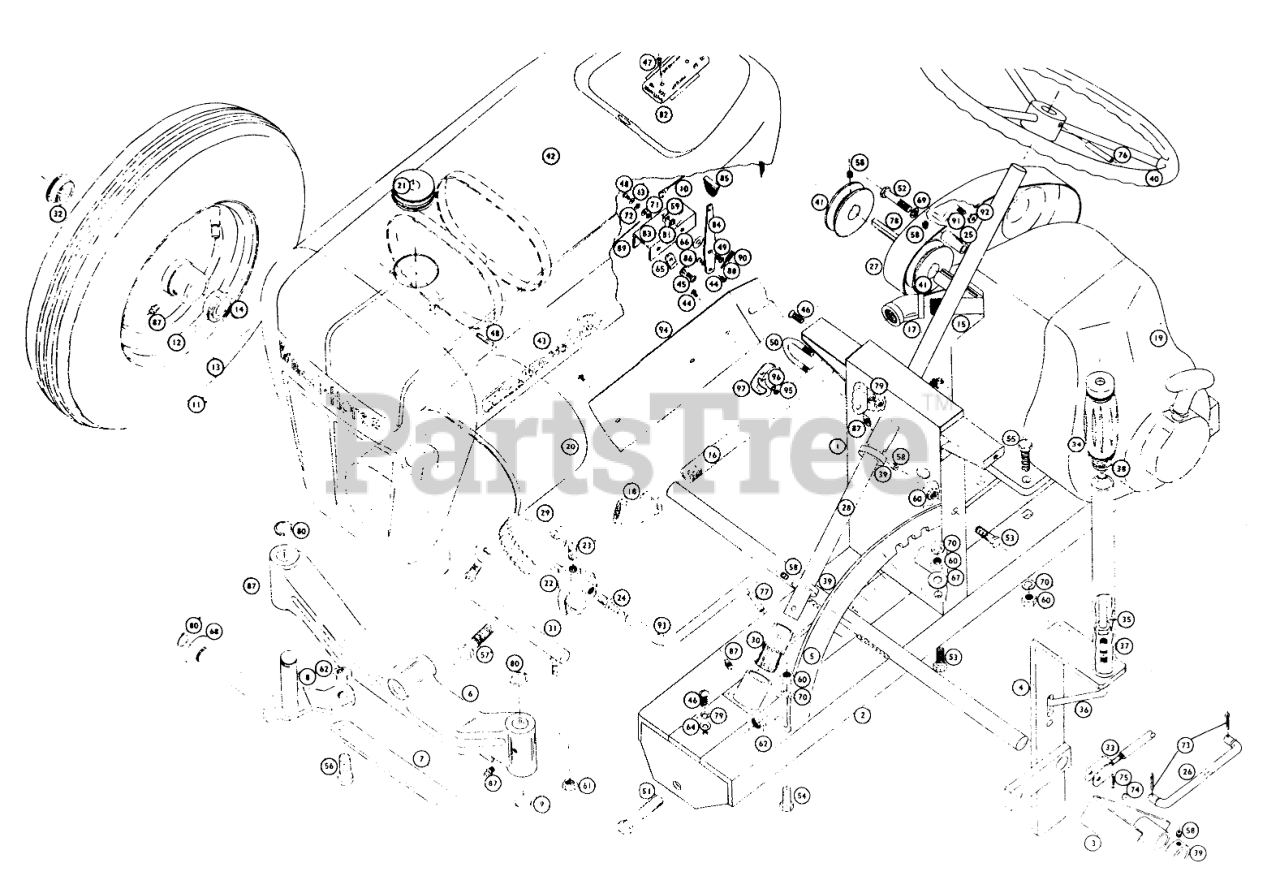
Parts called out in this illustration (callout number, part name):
1	Hood Stand Ass-y
2	Frame Ass-y
3	Clutch Pedal
4	Tool Lift Lever
5	Lift Sector
6	Front Axle
7	TIE ROD R
8	Front Spindle
9	Front Spindle
10	Wire Assy
11	Wheel
12	ASSY WHEEL & BEARING
13	Tire
13	Tube
14	Bearing Ball
15	Nipple Pipe
16	Nipple Pipe
17	Elbow
18	Elbow
19	Engine
20	Gas Tank
21	Cap
22	FUEL STRAINER
23	1/8 Pipe Nip
24	Straight Fitting
25	Spacer Belt Gd
26	Clutch Rod
27	Belt Guard
28	Steering Rod
29	Sector Steering
30	Pinion Steering
31	Drag Link
32	BEARING
33	Lift Cable
34	Grip
35	Upper Plunger Rod
36	Lower Plunger Rod
37	SPRING-COMPRESSION
38	Guide-Rod
39	Collar
40	Steering Wheel
41	Pulley
42	Hood
43	Crome Cal
44	Stove Bolt
45	Stove Bolt
46	Stove Bolt
47	Machine Screw
48	Stove Bolt
49	Stove Bolt
50	U-Bolt
51	Hex Head Cap
52	Hex Head Cap
53	Hex Head Cap
54	Hex Head Cap
55	Hex Head Cap
56	Clevis Pin
57	Hex Head Cap
58	Snap Ring
59	Lock Nut
60	Hex Nut
61	Hex Nut
62	Hex Nut
63	Washer
64	Washer
65	1277 WH 1967 TRACTO
66	1276/VAR. WH TRACTO
67	SPRING,2X3 SS
68	WASHER
69	Lock Washer 5/16
70	Lockwasher
71	Insulating Washer
72	Insulating Bushing
73	Cotter Key
74	Yoke Pin
75	Cotter Pin
76	RoIl Pin
77	Roll Pin
78	SQ KEY
79	Lockwasher, 1/4
80	Snap Ring
81	Spring
82	Cover-Control Plate
83	Channel-Con. Lever Mount
84	Control Lever
85	89-33093R REAR MOUN
86	Wire Lock
87	Zerk
88	Wire Throttle
89	Wire Choke
90	Casing
91	Spring
92	Jam Nut
93	Fuel Line
94	Exhaust Shield
95	Nut
96	Lock Washer
97	Clamp
